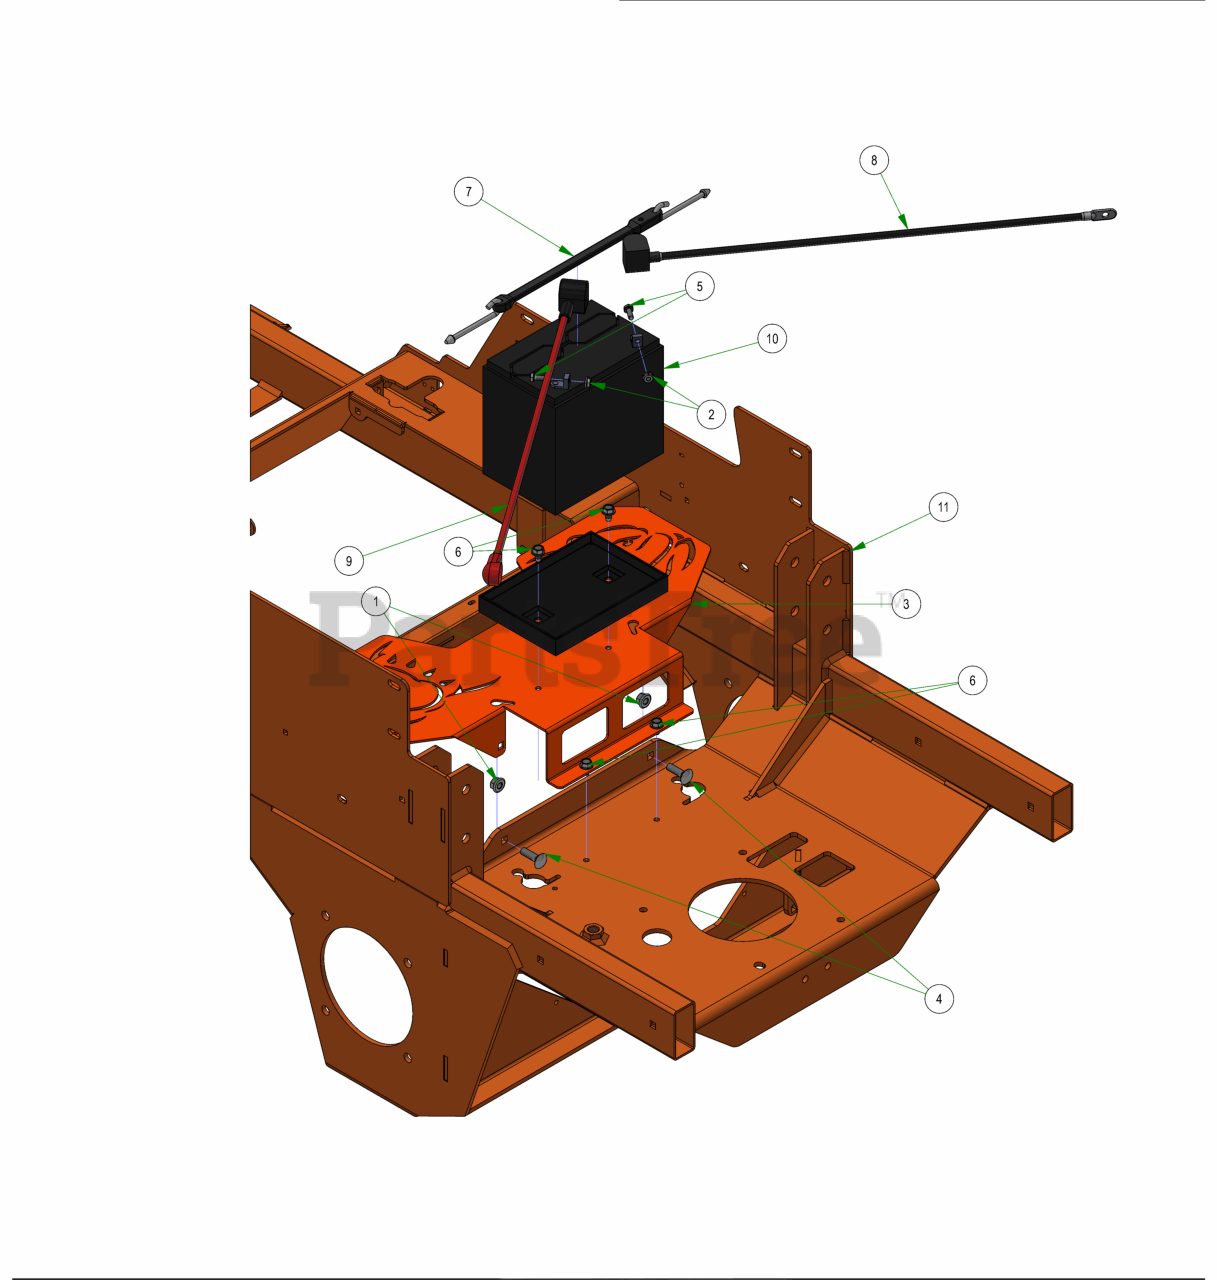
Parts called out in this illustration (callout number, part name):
1	3/8-16 NYLON INSERT FLANGE LOCKNUT (GR.F) ZINC
2	1/4-20 HEX SERRATED FLANGE NUT HARD/ZINC
3	Rigid X Fan Guard v1
4	3/8-16 X 1-1/4 CARRIAGE BOLT ZINC
5	1/4-20 X 3/4 HEX CAP SCREW (GR.5) ZINC
6	5/16-18 X 1/2 HWH unslot (F) tcs zinc
7	2023 Battery Hold Down Assembly
8	24" Black Cable
9	24" Red Battery Cable
10	SP-35 Battery
11	2023 Rebel Frame - Painted
